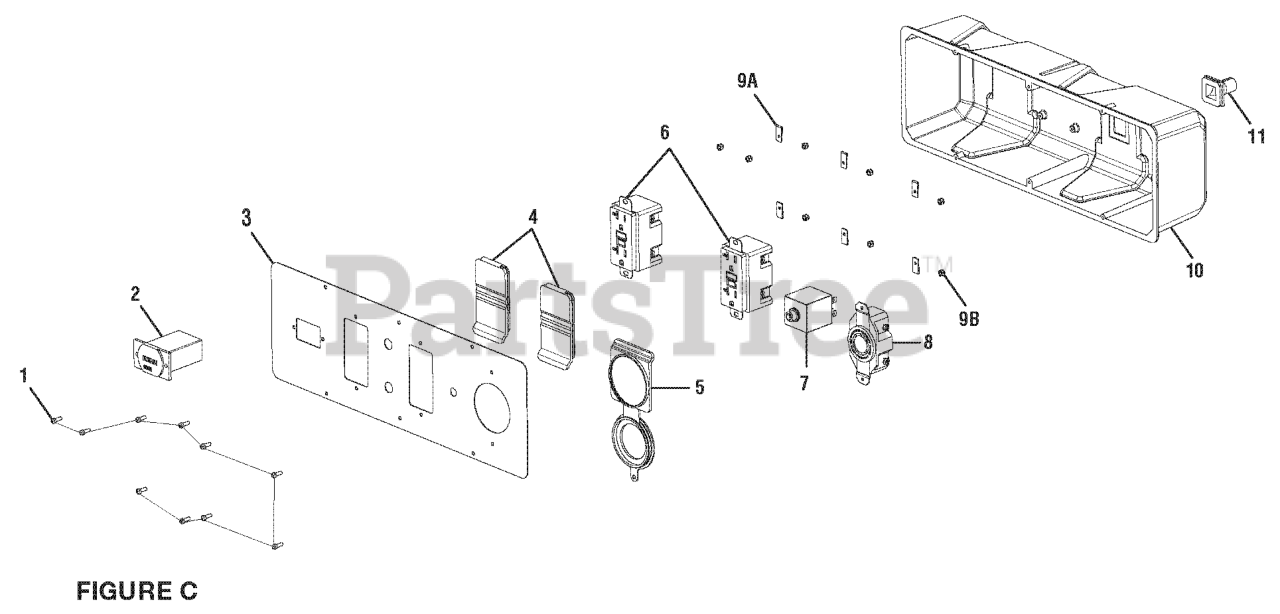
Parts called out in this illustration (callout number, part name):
1	Screw (6-20 x 3/8 in.)
2	Hour Meter (120 Volt)
3	Front Panel
4	Outlet Cover (120 Volt)
5	Outlet Cover (240 Volt)
6	120 Volt Duplex Receptacle (GFCI)
7	Circuit Breaker (20 Amp)
8	Twist Lock Receptacle (120/240 Volt, 30 Amp, L14-30R)
11	Control Box (Back Panel)
12	Rubber Boot
